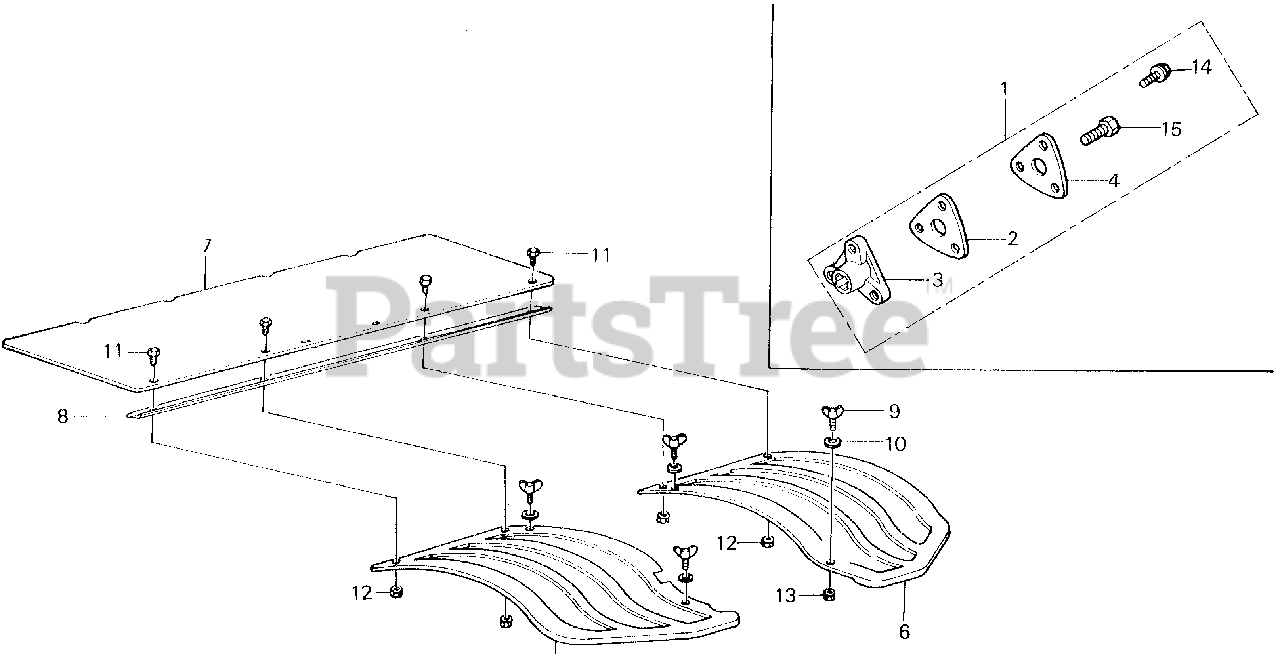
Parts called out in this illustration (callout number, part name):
1	BOSS KIT, P.T.O. PULLEY
2	SPACER, PULLEY
3	BOSS, P.T.O. PULLEY
4	PLATE, PULLEY
5	SUB-FENDER, R. *NH31* (MCKINLEY WHITE)
6	SUB-FENDER, L. *NH31* (MCKINLEY WHITE)
7	SPLASH GUARD
8	BAND, SPLASH GUARD SETTING
9	BOLT, WING (8MM)
10	WASHER, WING BOLT (NOT AVAILABLE)
11	BOLT, HEX. (6X12)
12	NUT, HEX. (6MM)
13	NUT, HEX. (8MM)
14	BOLT, FLANGE (6X16)
15	BOLT, FLANGE (8X16)
